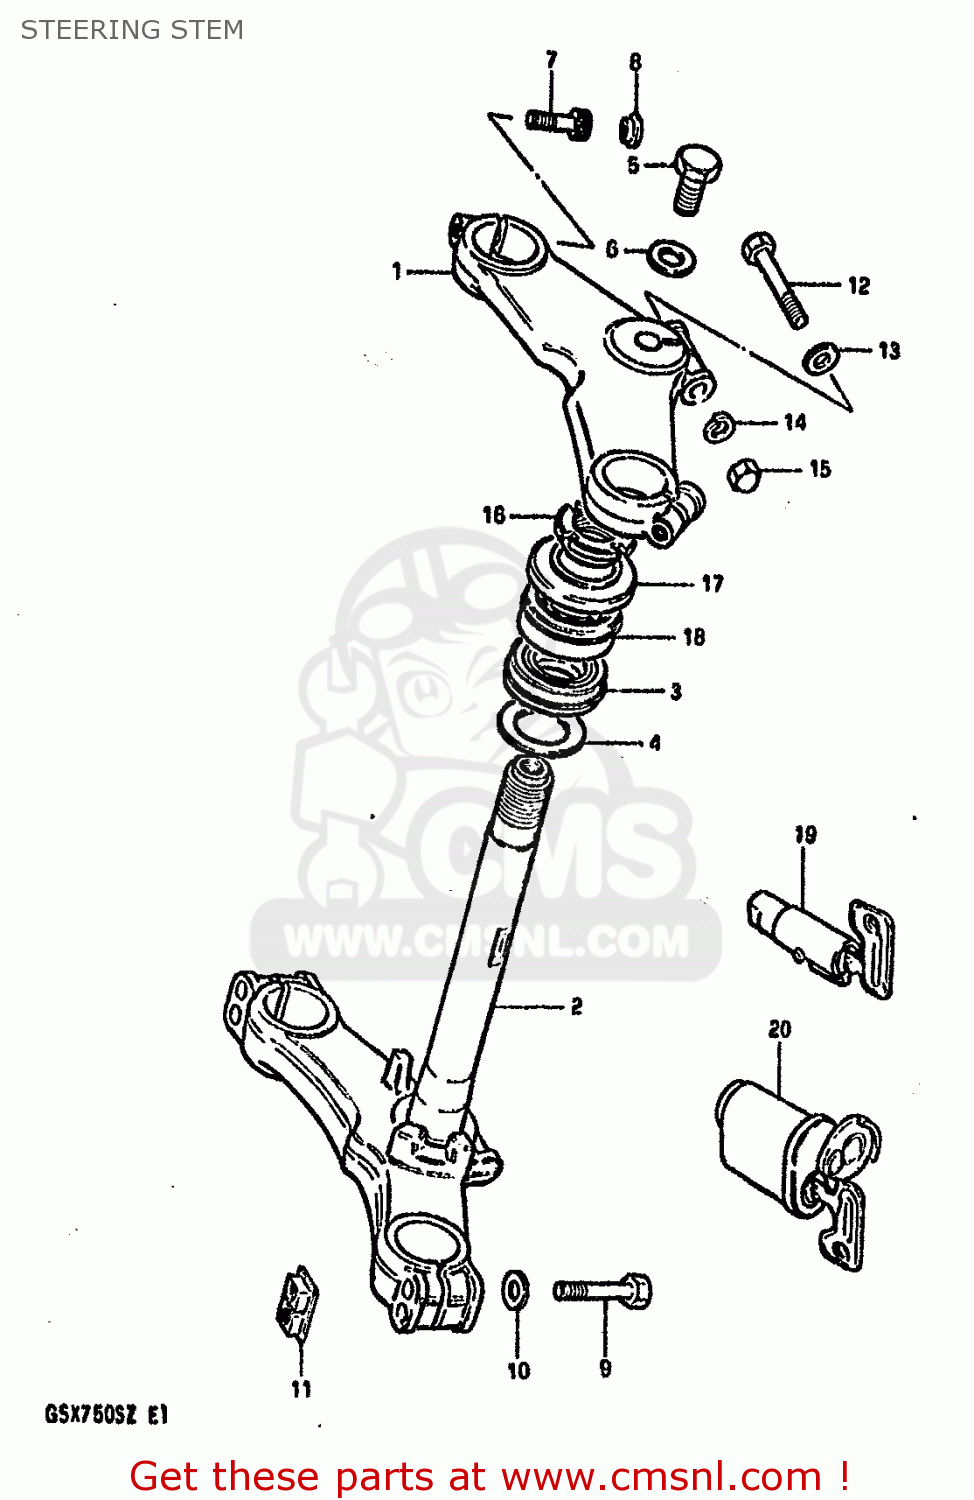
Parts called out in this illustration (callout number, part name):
1	STEM HEAD, STEERING (SILVER)
2	STEM, STEERING (SILVER)
3	BEARING
4	WASHER,THRUST
5	NUT,STEM HEAD
6	WASHER,STEERING STEM B
7	BOLT
8	CAP(OD:20)
9	BOLT 8X55
10	WASHER
11	NUT,FR FORK INNER TUBE
12	BOLT 8X50
13	WASHER
14	WASHER,LOCK,8.
15	NUT
16	NUT,STEERING STEM
17	DUST SEAL,STEERING,UPPER
18	TAPER,ROLLER BEARING
19	LOCK ASSEMBLY,STEERING (NEI
20	LOCK ASSY, STEERING (NEIMAN TYPE EXECUTE
